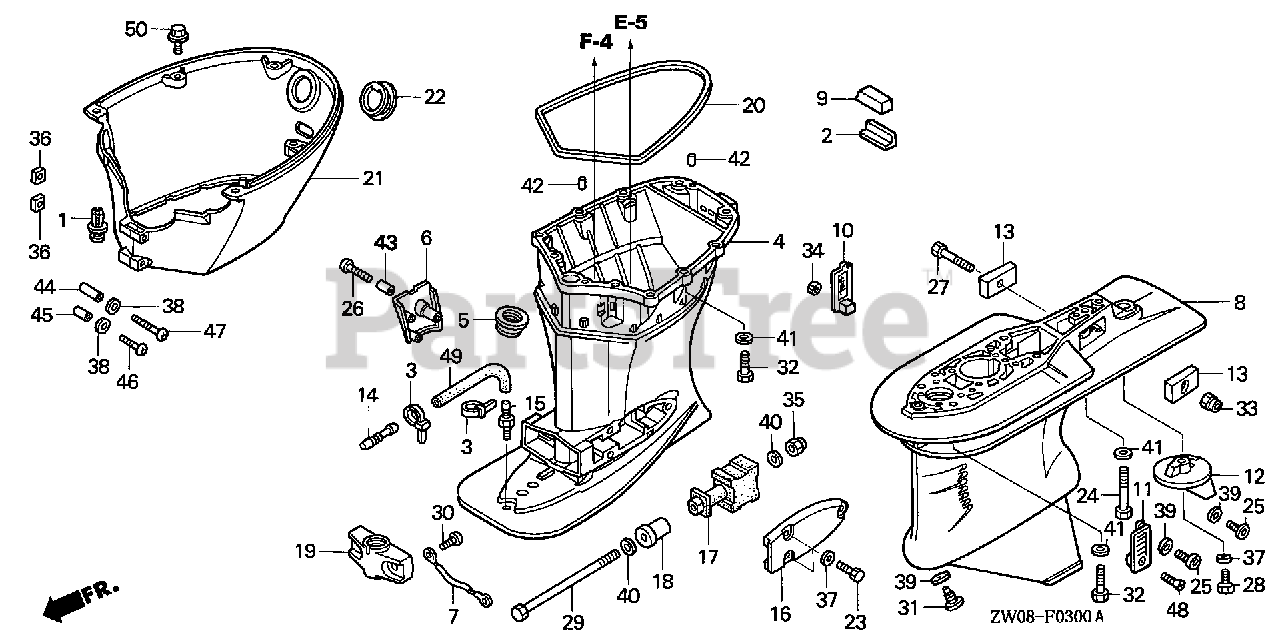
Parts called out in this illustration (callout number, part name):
1	CLIP, FUEL PIPE (BLACK)
2	PLATE, RUBBER SETTING
3	BAND, WIRE
4	CASE, EXTENSION *NH282MU* (L) (OYSTER SILVER METALLIC-U)
5	RUBBER, DRAIN PLUG
6	COVER, DRAIN PLUG *NH282MU* (OYSTER SILVER METALLIC-U)
7	WIRE, LEAD (1.5X116MM)
8	CASE, GEAR *NH282MU* (OYSTER SILVER METALLIC-U) (NA USE ALT:41101-ZW1-B05ZA)
9	GROMMET, GEAR CASE
10	SCREEN, R. WATER
11	SCREEN, L. WATER
12	TAB, TRIM *NH282MU* (OYSTER SILVER METALLIC-U)
13	METAL, ANODE
14	END, NIPPLE
15	NIPPLE, SENSOR
16	HOUSING, MOUNTING (LOWER) *NH282MU* (OYSTER SILVER METALLIC-U)
17	RUBBER, MOUNT (LOWER)
18	COLLAR, MOUNTING (LOWER)
19	HOUSING, CENTER MOUNTING (LOWER) *NH282MU* (OYSTER SILVER METALLIC-U)
20	SEAL B, COVER (LOWER)
21	COVER *NH282MU*
22	GROMMET, COVER (LOWER)
23	BOLT, HEX. (8X30)
24	BOLT, HEX. (10X80)
25	BOLT, OIL CHECK (8X8)
26	SCREW, SPECIAL (6X35)
27	BOLT, HEX. (6X32)
28	BOLT, HEX. (8X25)
29	BOLT, HEX. (12X225)
30	SCREW, PAN (6X8)
31	BOLT, DRAIN PLUG (8MM)
32	BOLT, HEX. (10X40)
33	NUT, SELF-LOCK (6MM)
34	NUT, SELF-LOCK (5MM)
35	NUT, SELF-LOCK (12MM)
36	NUT, PLATE (5MM)
37	WASHER, PLAIN (8MM)
38	WASHER, PLAIN (5MM)
39	WASHER, NYLON (8MM)
40	WASHER, PLAIN (12MM)
41	WASHER, PLAIN (10MM)
42	PIN, DOWEL (6X10)
43	COLLAR, DISTANCE (6X10.5X25)
44	COLLAR, DISTANCE (5X7X38)
45	COLLAR, DISTANCE (5X7X23)
46	SCREW, PAN (5X30)
47	SCREW, PAN (5X45)
48	SCREW, OVAL (5X45)
49	BULK HOSE, VACUUM (5X3000) (5X250)
50	BOLT, FLANGE (6X12)
